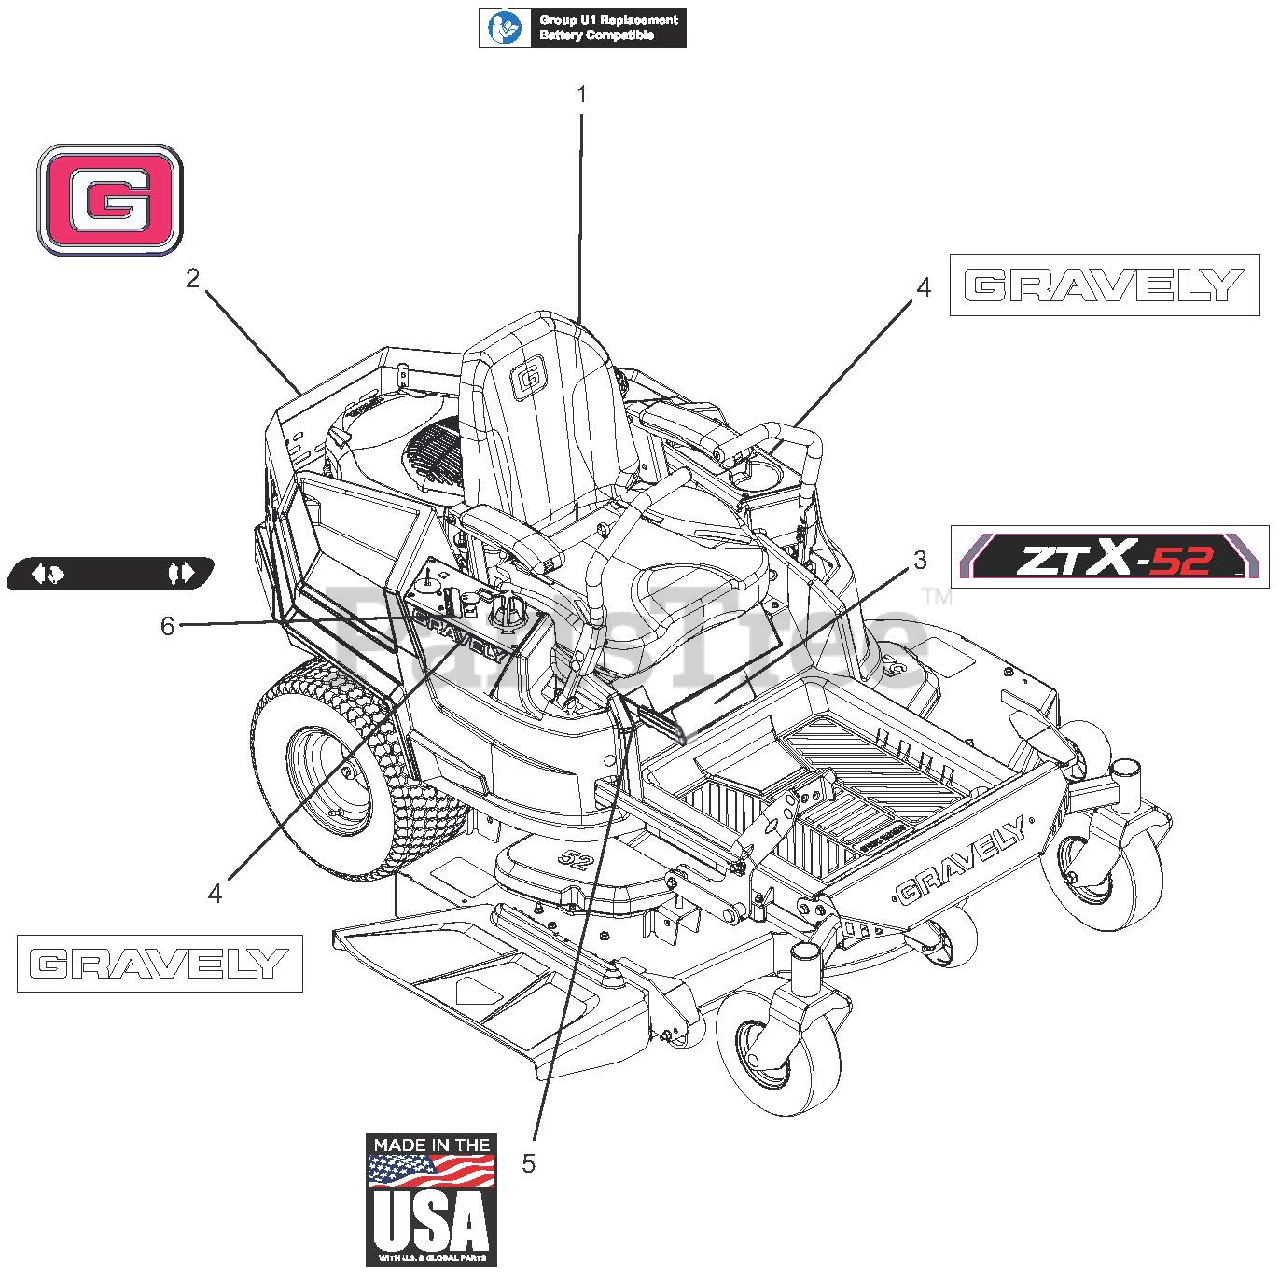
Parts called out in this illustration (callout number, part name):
1	DECAL, U1 BATTERY REPLACEMENT
2	DECAL, GRAVELY BRAND
3	DECAL, GRAVELY ZT X 52
4	DECAL, 9.5" GRAVELY LOGO
5	DECAL, MADE IN USA
6	DECAL, DASH DECAL
